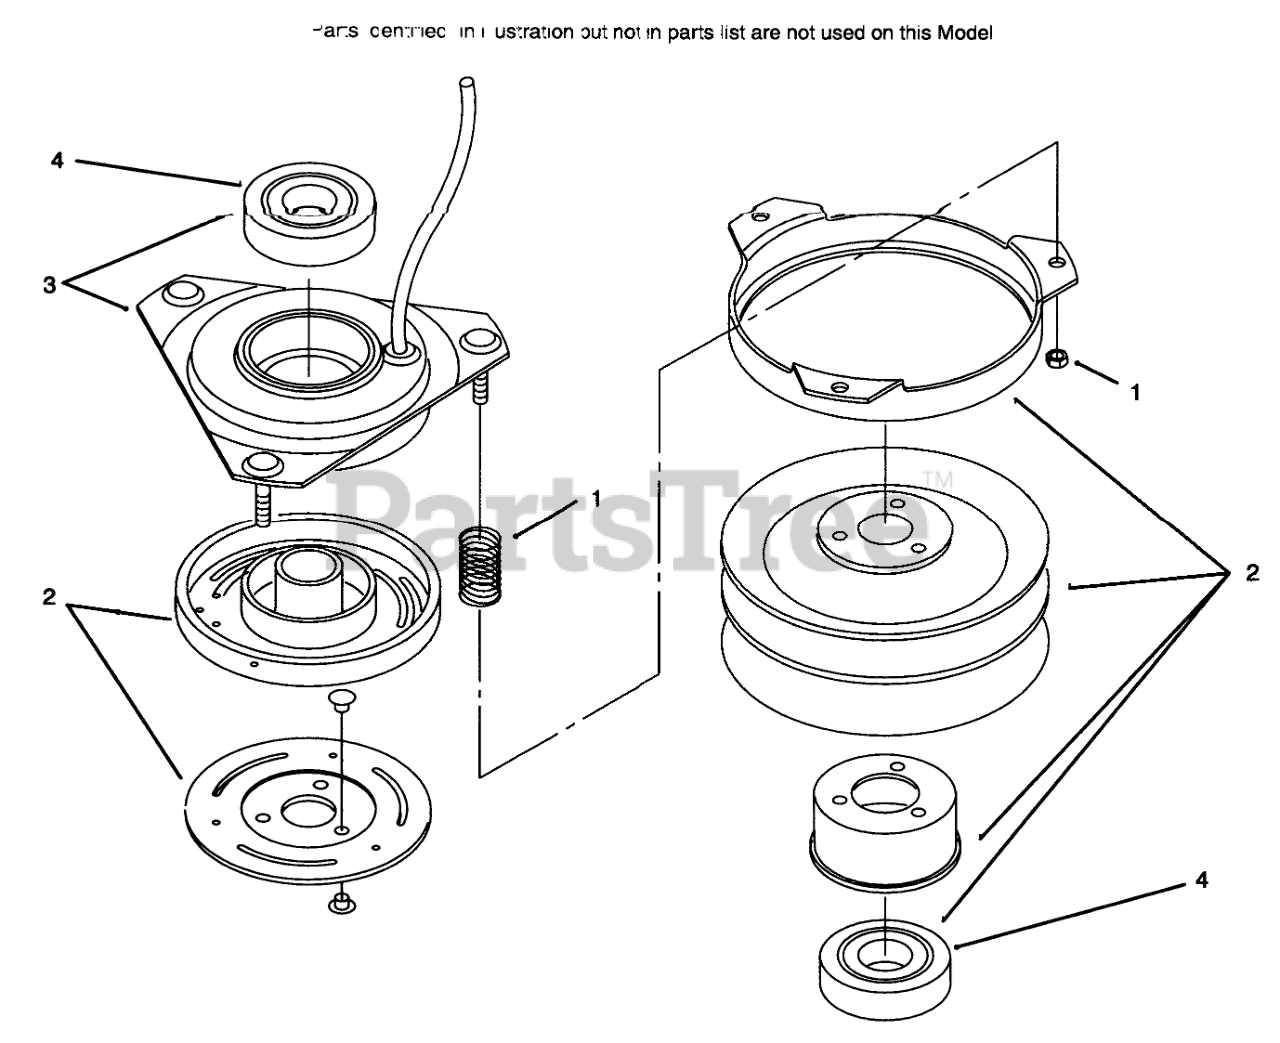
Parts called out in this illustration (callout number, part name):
1	ACCESSORY PKG SRVC PART
2	Rotor ASM W/Bearing (Only On: 72104)
2	Rotor & Armature ASM (Only On: 72085)
3	FIELD ASSY (SRVC PART)
4	BEARING-ELEC CLUTCH
